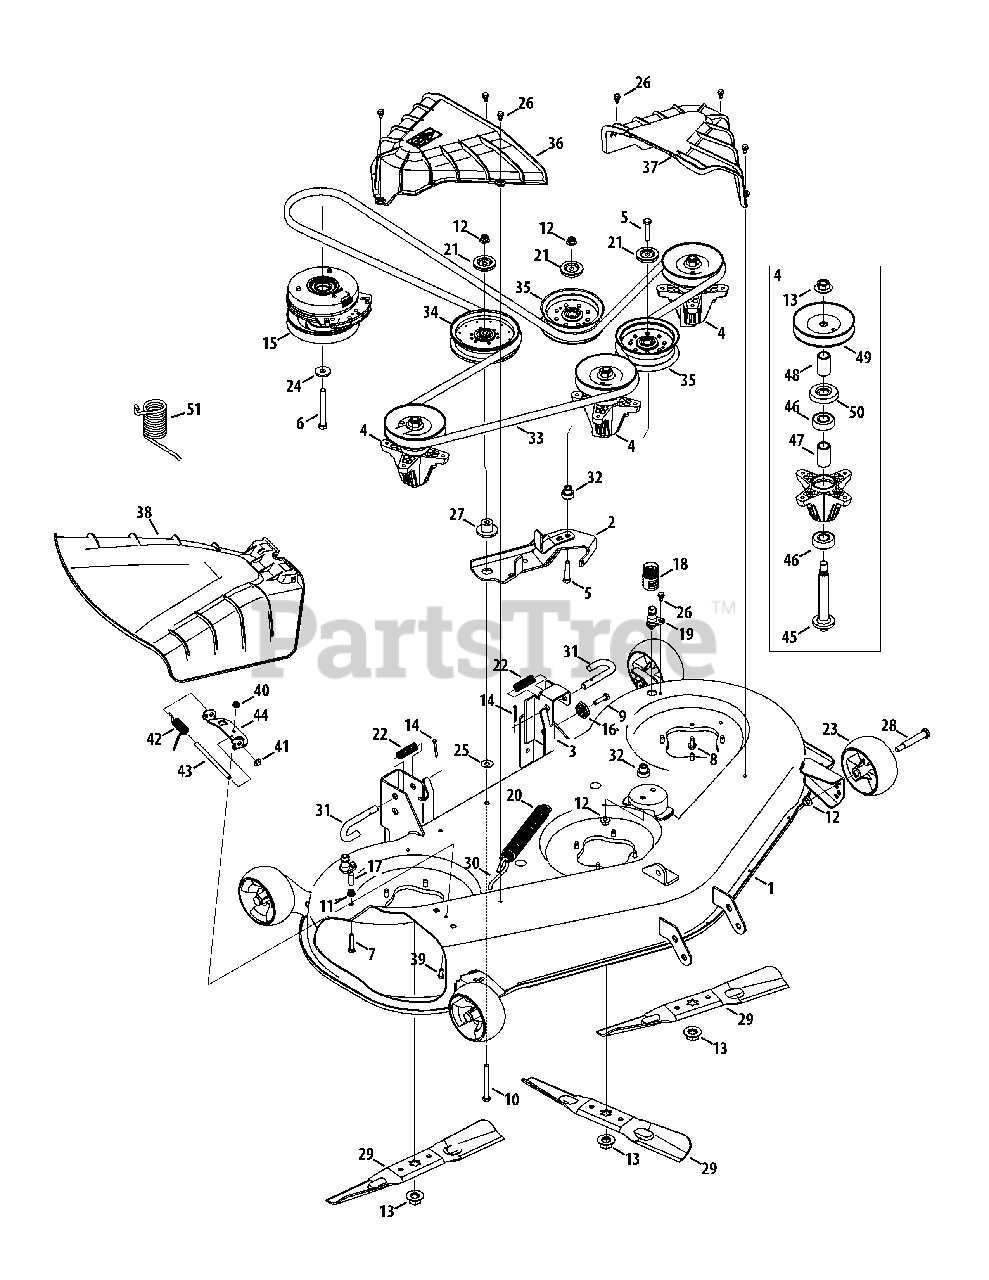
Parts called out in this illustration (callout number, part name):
1	50" Deck
2	Deck Idler Assembly
3	Deck Lift Bracket
4	Spindle Assembly
5	Hex Cap Screw, 3/8-16 x 1.75
6	Hex Cap Screw, 7/16-20 x 3.50
7	Hex Head Screw, 5/16-18 x 1.50
8	Hex Washer Screw, 5/16-18 x .750
9	Hex Flange Screw, 3/8-16
10	Hex Bolt 3/8-16 x 3.25"
11	Flange Lock Nut, 5/16-18
12	Flange Lock Nut, 3/8-16
13	Hex Flange Nut, 5/8-18
14	Cotter Pin, 5/32 x 1.25
15	Clutch, Electric PTO
16	Deck Adjustment Gear
17	Vinyl Cap, .29 x 1.00
18	Water Nozzle Adapter
19	Deck Wash Nozzle
20	Extension Spring, 1.25 OD x 1.751
21	Pulley Cap
22	Compression Spring, .66 x 1.9
23	Deck Ball Wheel, 5.0
24	Flat Washer, .450 x 1.25 x .164
25	Flat Washer, .385 x 1.0 x .030
26	Shoulder Screw, 1/4-20 x 0.50
27	Shoulder Spacer
28	Shoulder Screw, .5 x 2.5 x 3/8-16
29	Blade, Cut, 17.27" 2-In-1
30	Deck Spring Rod
31	Deck Hanger Rod
32	Shoulder Spacer
34	Idler Pulley, 5.00 Dia.
35	Pulley, Idler, 4.50" Dia.
36	Belt Cover, RH
37	Belt Cover, LH
38	Chute Deflector Assembly
39	Hex Cap Screw, 1/4-20 x .62
40	Nut, Flange Lock, 1/4-20, Nylon
41	Push Cap
42	Spring, Torsion, .440 ID x 1.75
45	Spindle Shaft, 6.11 Long
46	Ball Bearing
47	Spacer, .792 x 1.060 x 1.860
48	Spacer, .792 x 1.060 x 1.782
49	Deck Pulley
50	Bearing Shield
51	Torsion Spring, 1.323 ID x 2.83 LG
